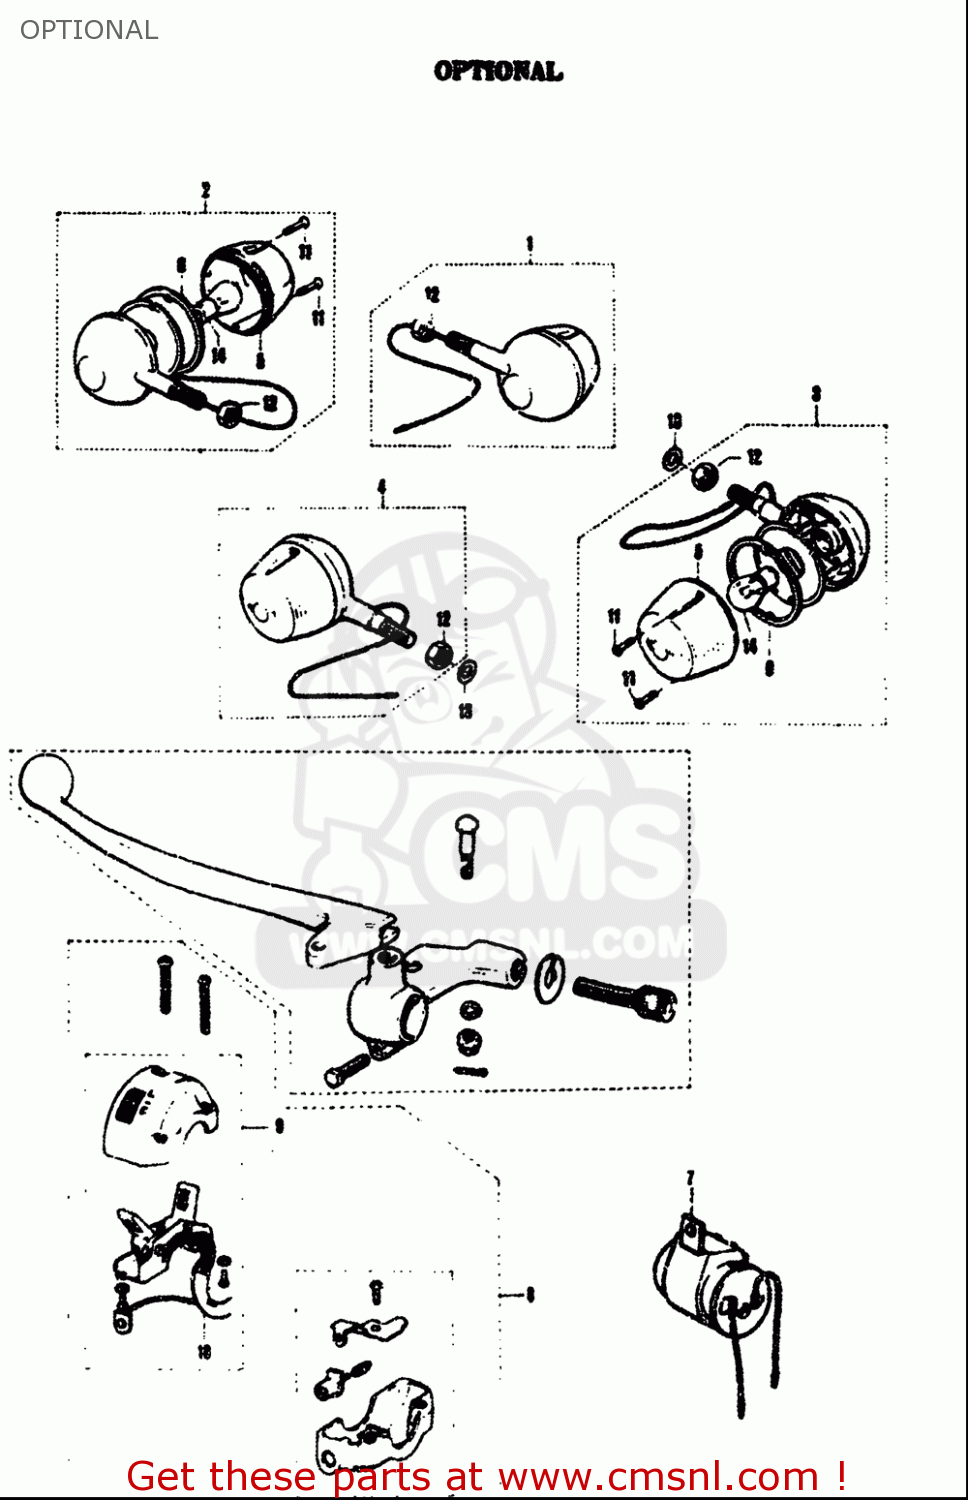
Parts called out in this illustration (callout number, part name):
1	LAMP ASSY,FR TURN SIGNAL
5	LENS,TURNSIGNAL
6	GASKET,TURNSIGNAL LENS (NAS)
11	SCREW
12	NUT
13	WASHER
